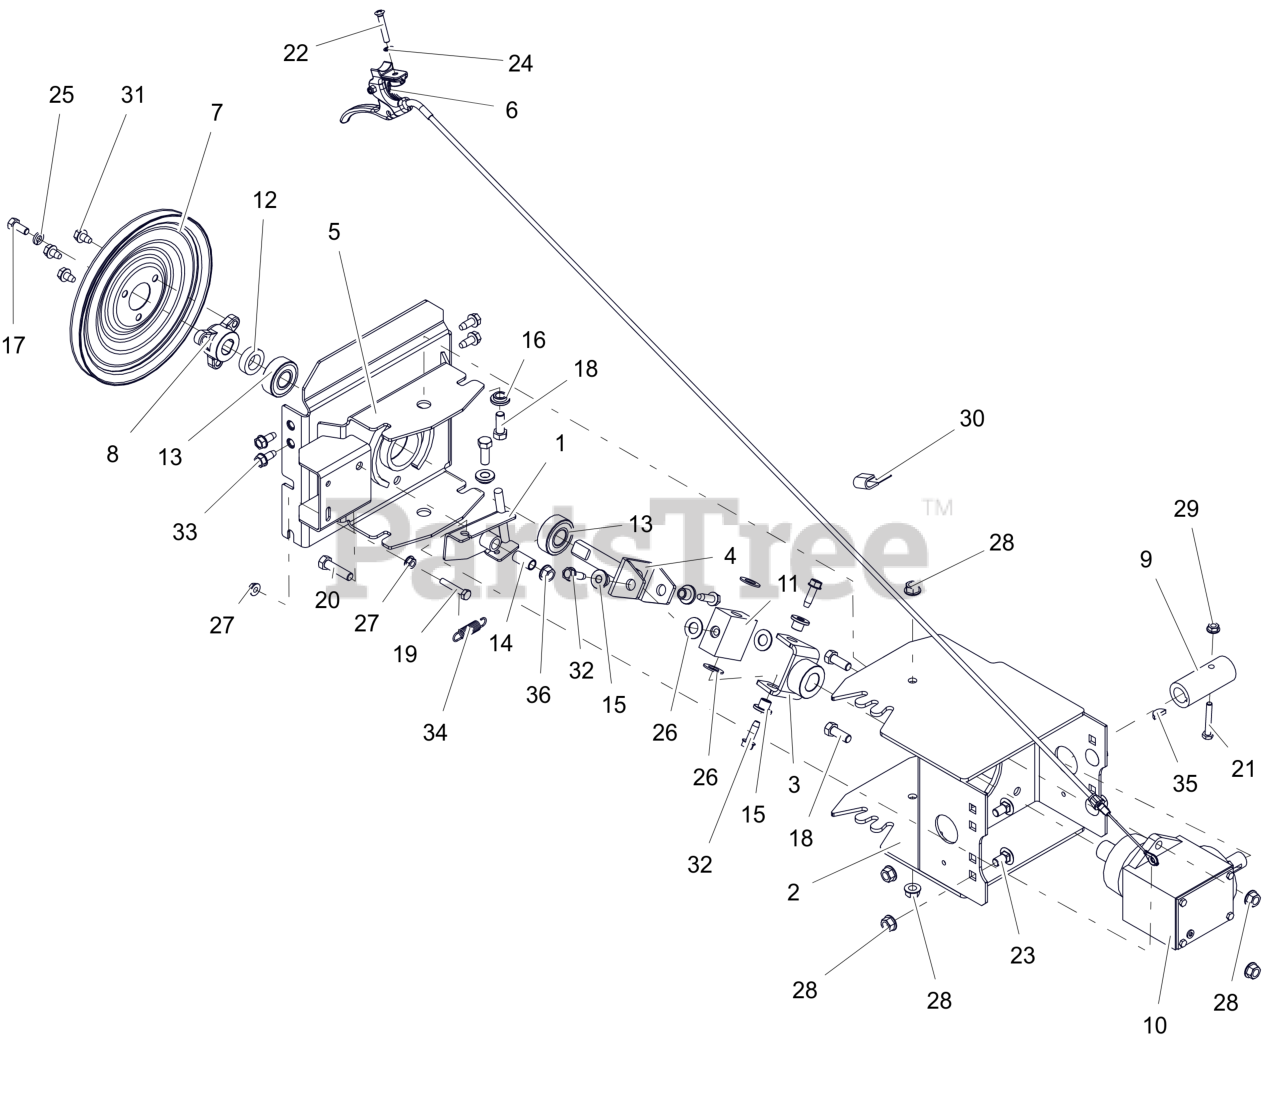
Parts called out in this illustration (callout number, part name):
1	ARM, PIVOT LOCK
2	ADAPTER, BROOM FRAME
3	JOINT,UNIVERSAL
4	JOINT,UNIVERSAL
5	ADAPTER, FRAME-20000 SERIES
6	CABLE, REMOTE BRUSH LOCK
7	PULLEY,SPIN FORM SINGLE GROOVE
8	PULLEY HUB, BOLT-ON D-BORE .75
9	HUB, COUPLING
10	GEAR BOX ASSEMBLY
11	BLOCK, UNIVERSAL
12	SPACER .755X1.250X.370
13	BRG-BALL .750X1.781X.61
14	BSHG-SLV .385X.500X1.045
15	BSHG-FLG .325X.500X.513X.875
16	BSHG-FLG .406X.88X.270X.140
17	BLT, HEX .31-24X.750 G5 ZCC
18	BLT,HEX .38-16X1.00 G5 ZCC
19	BLT, HEX .25-20X1.50 G5 ZCC
20	BLT, HEX .38-16X1.50 G5 ZCC
21	@BLT-HEX .25-20X1.75 GR5 YWZC
22	SCR,OVAL .25-20X1.50 ZCC
23	BLT, RHSN .38-16X.750 G5 ZCC
24	WSHR-LK-INT .250 TH TYA
25	WSHR, LK-HVY .312X.097 ZCC
26	WSHR-HDND-STL-THR.515X.97X.062
27	NUT-SPNLK-FLG .25-20 ZC120
28	NUT-LK-TOP-FLG .38-16 ZC120
29	NUT-LK-TOP-FLG .250-20 GF ZCC
30	J-CLAMP
31	SCR,TAP .312-18X.50 HWH TR ZCC
32	SCR,TAP .31-18X1.00 HWH TR ZCC
33	SCR,TAP .312-18X.75 HWH TR ZCC
34	SG-TENS .06X.46X2.00
35	KEY-WDRF .188X.75X.313 SAE 9
36	NUT-LK-CTR-FLG .375-16 GF ZCC
